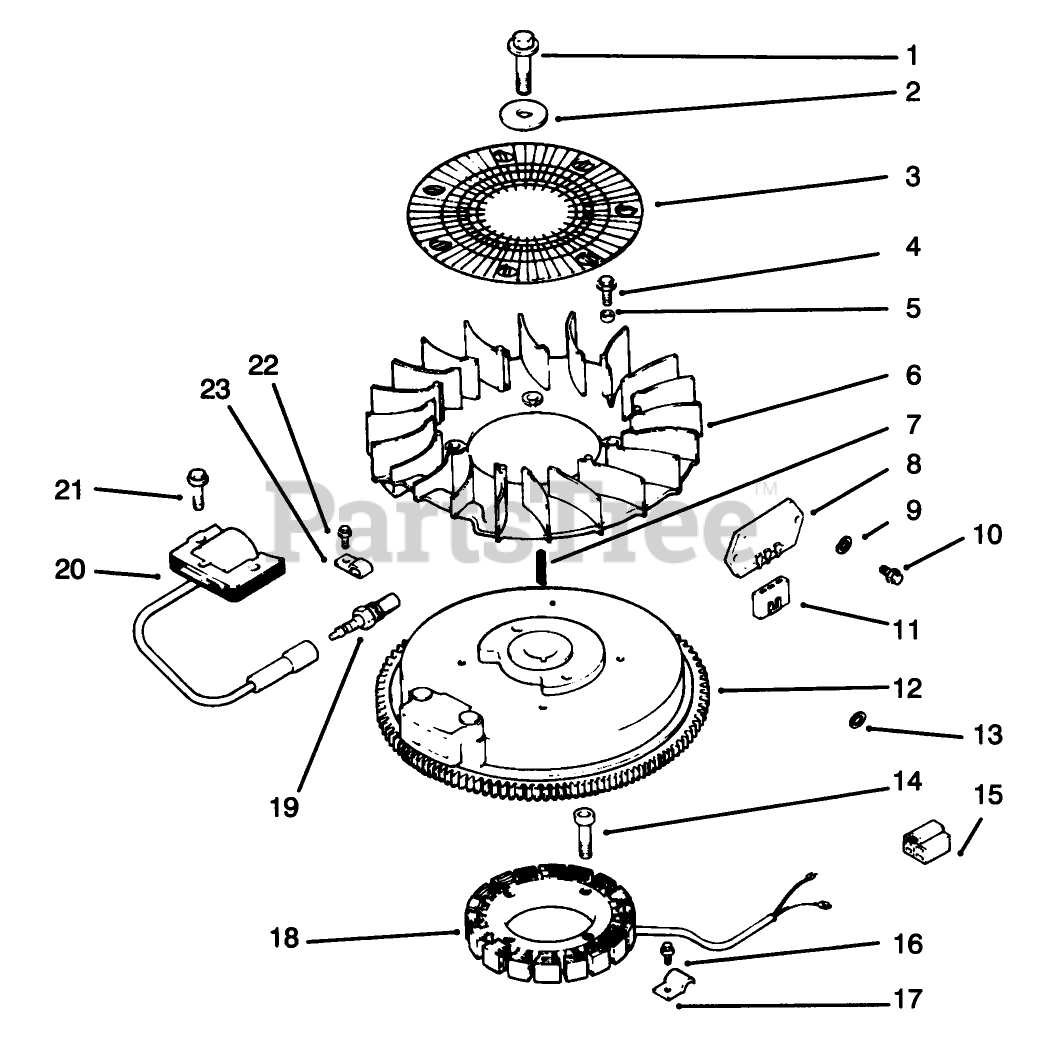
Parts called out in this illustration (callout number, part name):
1	Screw
3	Screen-Grass (Only On: 72042, 72063, 72062, 72043)
5	Spacer-Fan
6	Fan (Only On: 72042, 72063, 72062, 72043)
8	Rectifier-Regulator (Only On: 72042,72043,72062,72063)
9	Washer-Lock (Only On: 72042, 72063, 72062, 72043)
11	Connector
12	Flywheel ASM (Only On: 72042, 72063, 72062, 72043)
13	Washer-Flat (Only On: 72042, 72063, 72062, 72043)
15	Connector
17	Clip-Stator Harness (Only On: 72042, 72063, 72062, 72043)
18	Stator-15 amp
19	Spark Plug
20	Module-Ignition (Only On: 72042,72043,72062,72063)
